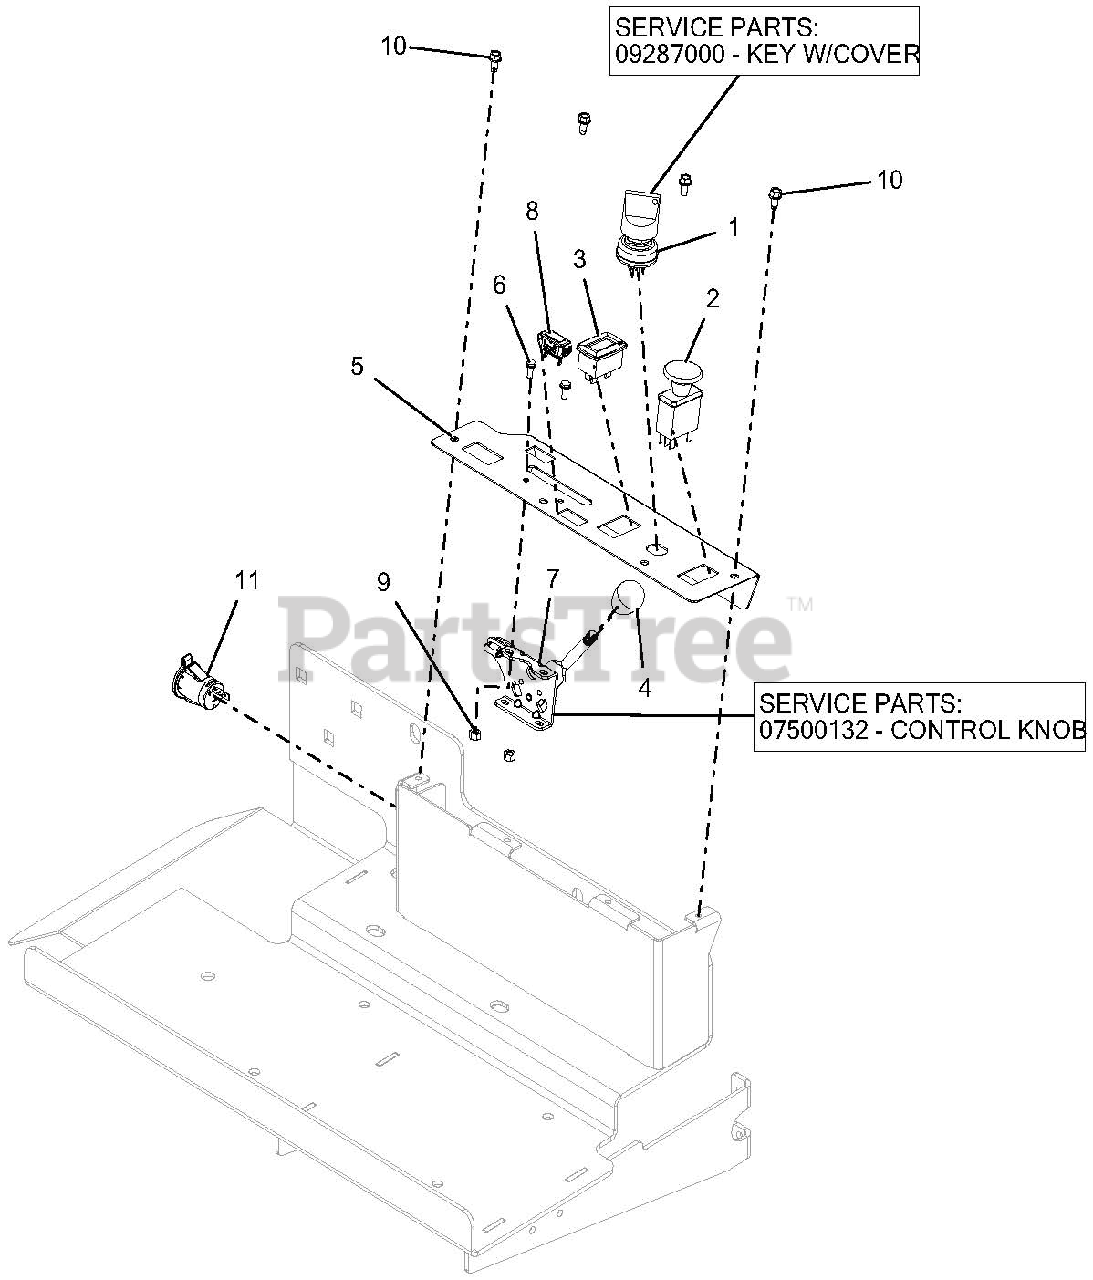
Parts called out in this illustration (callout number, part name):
1	SWITCH, IGNITION
1	KEY W/ COVER
2	SWITCH, CLUTCH
3	METER, HOUR W/MAINTENANCE
4	KNOB, CONTROL BLACK .38-16X.50
5	PANEL, CONTROL PT400 - LP
6	SCR-MCH 10-24X.5 HWH YWZC
7	CABLE, PRO-CONTROL THROTTLE
7	CONTROL KNOB
8	LIGHT, INDICATOR
9	NUT-LK-NYL #10-24 YWZC
10	SCR-TAP .25-20X.50 HWH TR YWZ
11	PORT, 12 VOLT POWER
